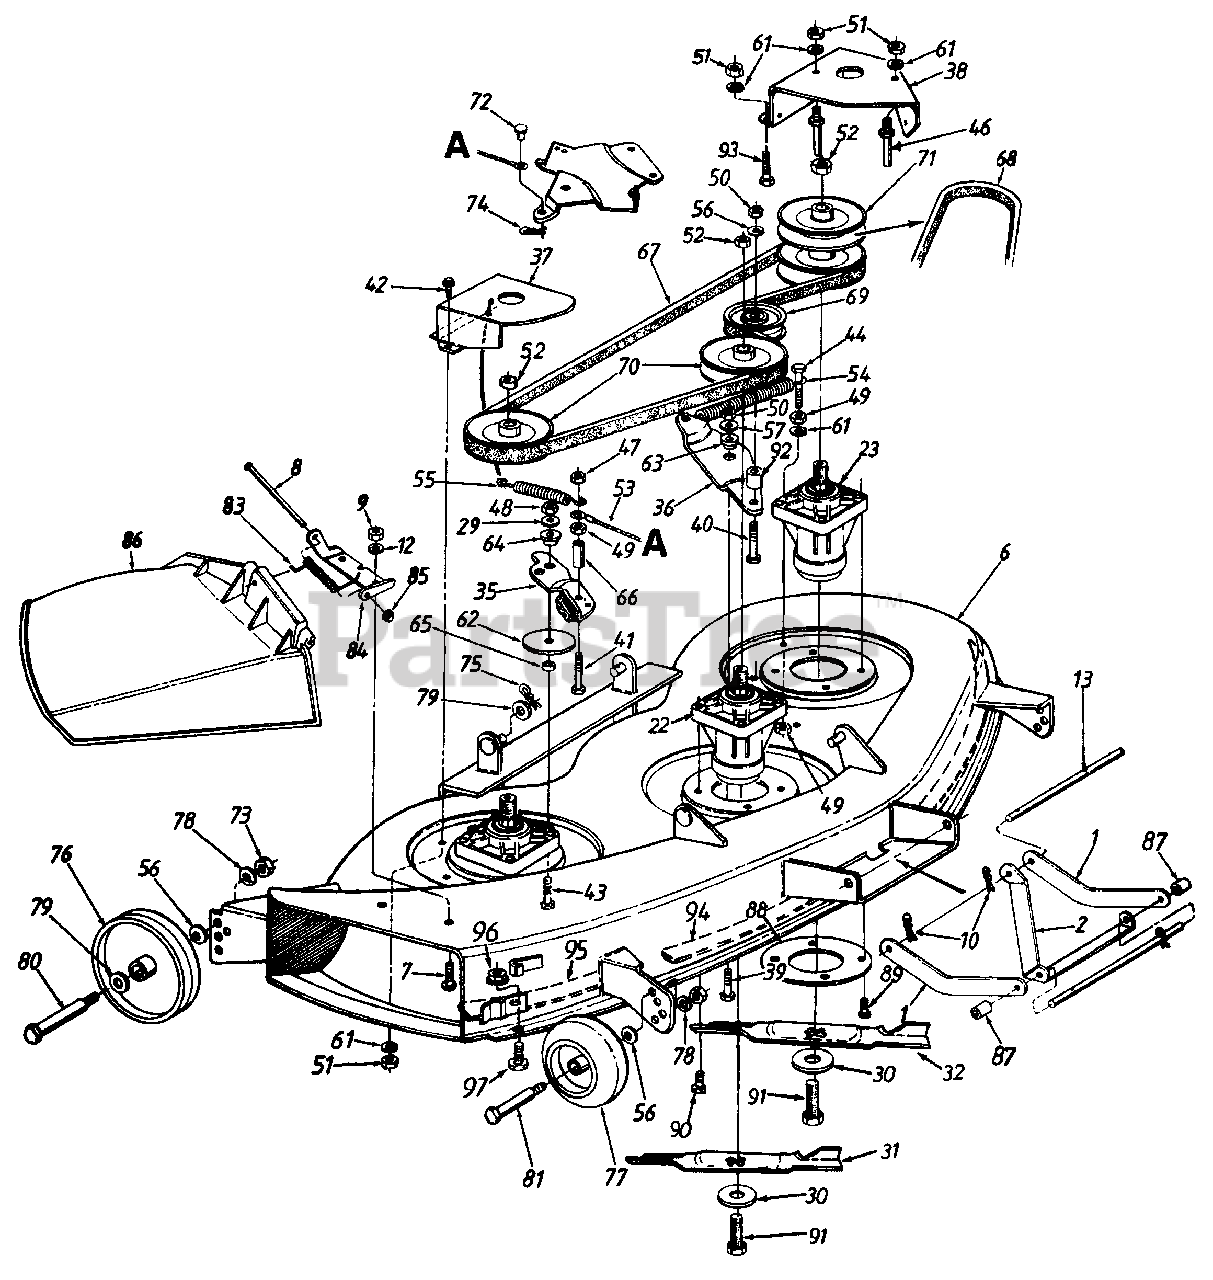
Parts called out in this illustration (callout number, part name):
8	Hinge Pin
9	Hex Nut 1/4-20 Thd.
10	Hairpin Clip
12	Bell-Wash. 1/4" I.D.
13	Deck Connecting Rod
22	Spindle Ass'y. (R.H. & Center)
23	Spindle Ass'y. (L.H.)
29	Lock Wash. 5/16" I.D.
30	Bell-Wash .47" I.D. x 1.5"
31	High Lift Blade 14.88" Lg. (Middle)
32	High Lift Blade 16.28" Lg. (R.H. & L.H.)
35	Deck Brake Brkt. Ass'y.
36	Idler Bracket
39	Hex Bolt 3/8-24 x 1.0" Lg.
40	Hex Bolt 3/8-24 x 2" Lg.
41	Hex Bolt 1/4-28 x 1.75" Lg.
42	Hex Wash. Hd. Tap-Scr. 1/4-20 x .5" Lg.
43	Hex Bolt 5/16-24 x 1.5" Lg. (Grade 5)
44	Hex Bolt 1/4-28 x 1.5" Lg.
46	Belt Guard Pin 1/4" Dia.
47	Hex Cent. L-Nut 1/4-28 Thd.
48	Hex Nut 5/16-24 Thd.
49	Hex Nut 1/4-28 Thd.
50	Hex Nut 3/8-24 Thd.
51	Hex Nut 1/4-20 Thd.
52	Hex Flange L-Nut 5/16-18 Thd.
53	Brake Cable Ass'y.
54	Extension Spring 6.17" Lg.
55	Extension Spring 3.97" Lg.
56	Bell-Wash .38" I.O. x .88" O.D.
57	Bell-Wash .39" I.D. x 1.13" O.D.
61	L-Wash. 1/4" I.D.
62	Fl-Wash. 5/16" I.D. x 3" O.D.
63	Shld. Spacer .625" I.D.
64	Shld. Spacer
65	Spacer .34" I.D.
66	Spacer .326" I.D.
67	V-Belt
68	V-Belt
69	Fl-Idler Pulley 3.5" O.D.
70	Pulley 5.0" Dia.
71	Double Pulley 5.0" Dia.
72	Clevis Pin 1/4" Dia. x .53" Lg.
73	Hex Nut 3/8-16 Thd.
74	Intern. Cotter Pin 5/16" Dia.
75	Intern. Cotter Pin 3/8 Dia.
76	Deck Wheel 5" Dia.
77	Deck Wheel w/Insert 5" Dia.
78	L-Wash. 3/8" I.D.
79	Fl-Wash .531" I.D.
80	Shoulder Bolt .498" Dia. x 1.64" Lg.
81	Shoulder Bolt
83	Torsion Spring
84	Hinge Mtg. Brkt.
85	Push Nut
86	Chute Ass'y. Comp.
87	Spacer 5/8" I.D. x 7/8" O.D.
90	Hex Wash. Hd. Scr. 5/16-18 x .75" Lg.
91	Hex L-Bolt 7/16-20 x 1" Lg. (Gr. 5)
92	Spacer .38" I.D.
93	Hex Bolt 1/4-20 x .5" Lg.
96	Hex Sems Nut 1/4-20 Thd.
97	Carriage Bolt 1/4-20 x .5" Lg.
